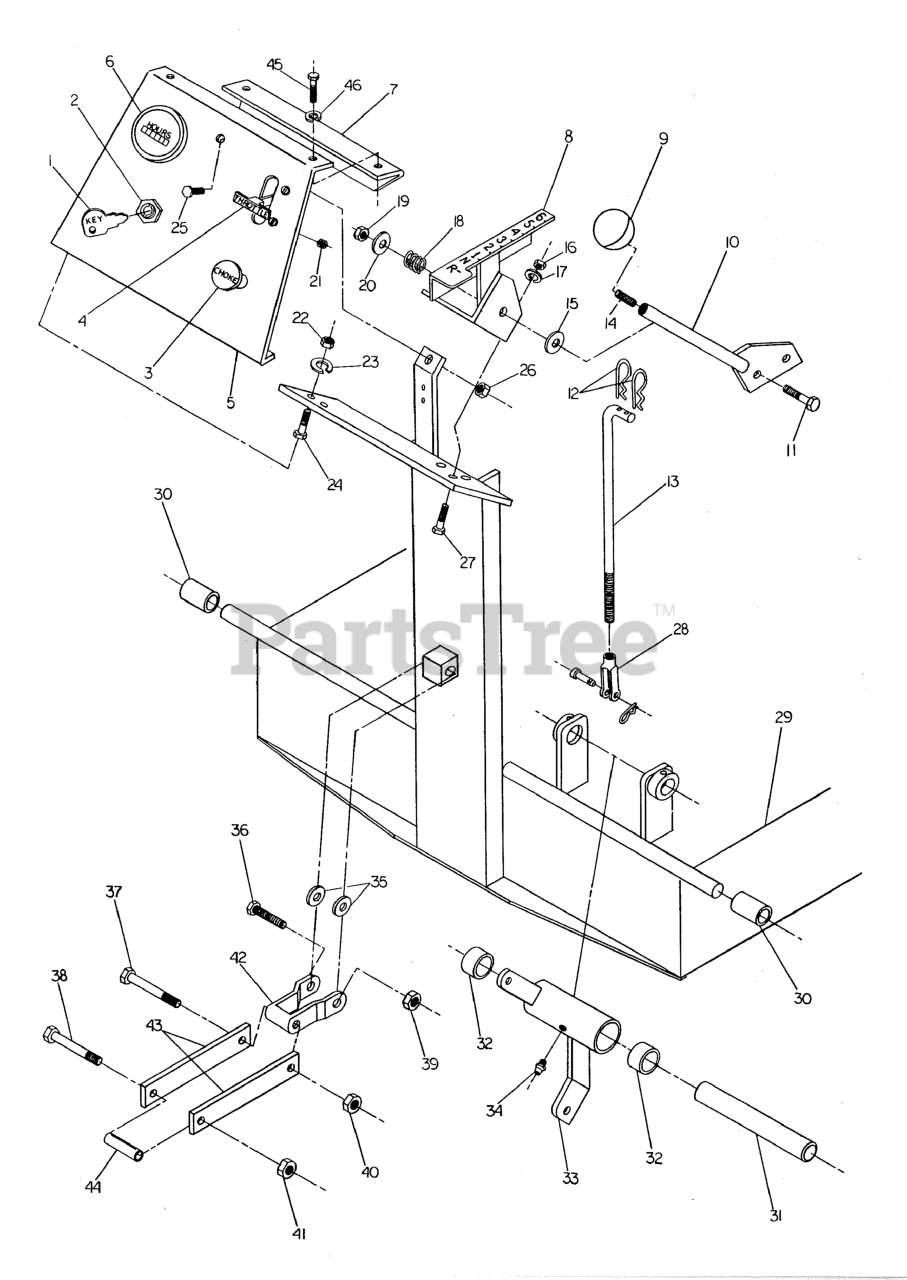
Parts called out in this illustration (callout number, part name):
1	Ignition Key
2	SWITCH, Ignition
3	CABLE, CHOKE CONTROL, 45
4	CABLE, Throttle, 31"
5	Control Panel
6	HOUR METER
7	Kohler Control Panel Cover
8	Shifter Guide
9	Black Knob
10	Shifter Handle
11	3/8-16 x 2 GD 5 Bolt
12	HAIRPIN CLIP
13	Shifter Adjustment Rod
14	STUD, 5/16-18 x 1"
15	3/8 Flat Washer
16	1/4-20 Nut
17	1/4" Lock Washer
18	SPRING, Compression
19	3/8-16 Locknut
20	3/8 Flat Washer
21	10/32 Nut
22	1/4 Nut
23	1/4" Lock Washer
24	1/4-20 x 3/4 HHCS
25	5/16-18 x 1 HHCS
26	5/16-18 SFN
27	1/4-20 x 1 HHCS
28	CLEVIS, 3/8-24, Plastic
29	Engine Deck
30	5/8 Heater Hose 1-1/2" Long
31	3/4" Diameter Shafting 6-1/4"
32	BUSHING, Brass
33	Transmission Bell Crank
34	GREASE FITTING
35	3/8 Flat WAsher
36	3/8-16 x 2 GD 5 Bolt
37	5/16-18 x 2-1/4 GD 8 Bolt
38	5/16-18 x 2-1/4 GD 8 Bolt
39	3/8-16 Lock Nut
40	5/16-18 Lock Nut
41	5/16-18 Lock Nut
42	Coupler Link
43	Electric Lift Linkage
44	Actuator Spacer
